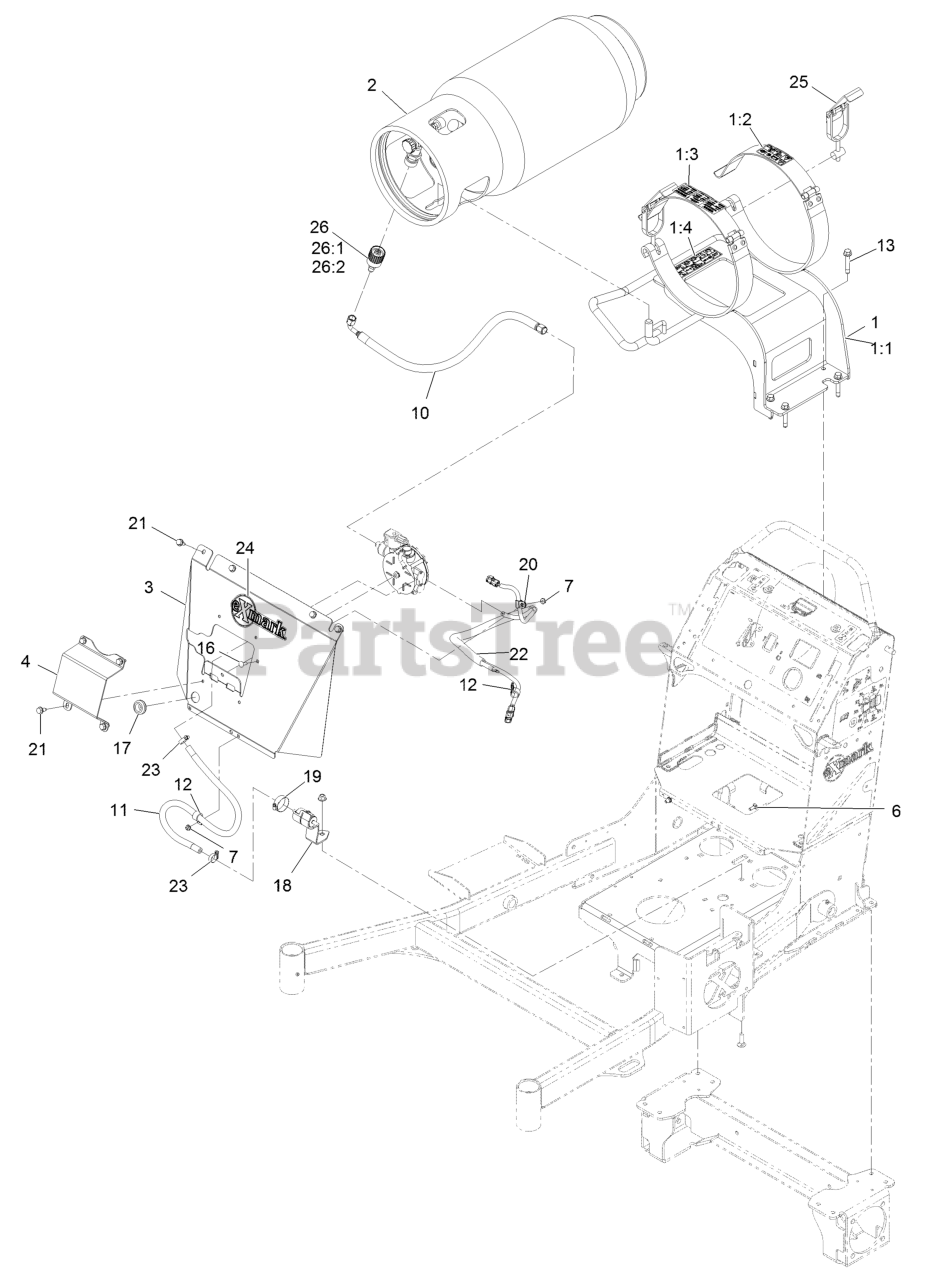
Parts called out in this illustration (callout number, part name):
1	ASM, LP TANK MOUNT W/ DEC
1:1	BRACKET-LPG TANK
1:2	Decal-LPG Warning
1:3	Decal-LPG Horiz Tank Spec
1:4	Decal-LPG Fuel Tank Replacement
2	TANK, LP - 33.5 LB.HORIZO
3	PANEL, FRONT
4	GUARD, REGULATOR
6	BOLT-CARR
10	ASM-HOSE, LPG
11	HOSE, FUEL
12	CLAMP-CABLE
13	SCREW-HHF W/ PATCH
16	SCREW-CARR
17	GROMMET
18	BRACKET, FILTER
19	CLAMP-HOSE
20	CLIP-LOOM
21	Screw-HWH 5/16-18 X 3/4 Tf
22	ASM, VENT HOSE AND HARNES
23	CLAMP-HOSE
24	DECAL, EXMARK LOGO
25	LATCH, LP TANK
26	CONNECTOR-LP, STRAIGHT
26:1	CONNECTOR-LPG TANK, LH TH
26:2	FITTING-STR
